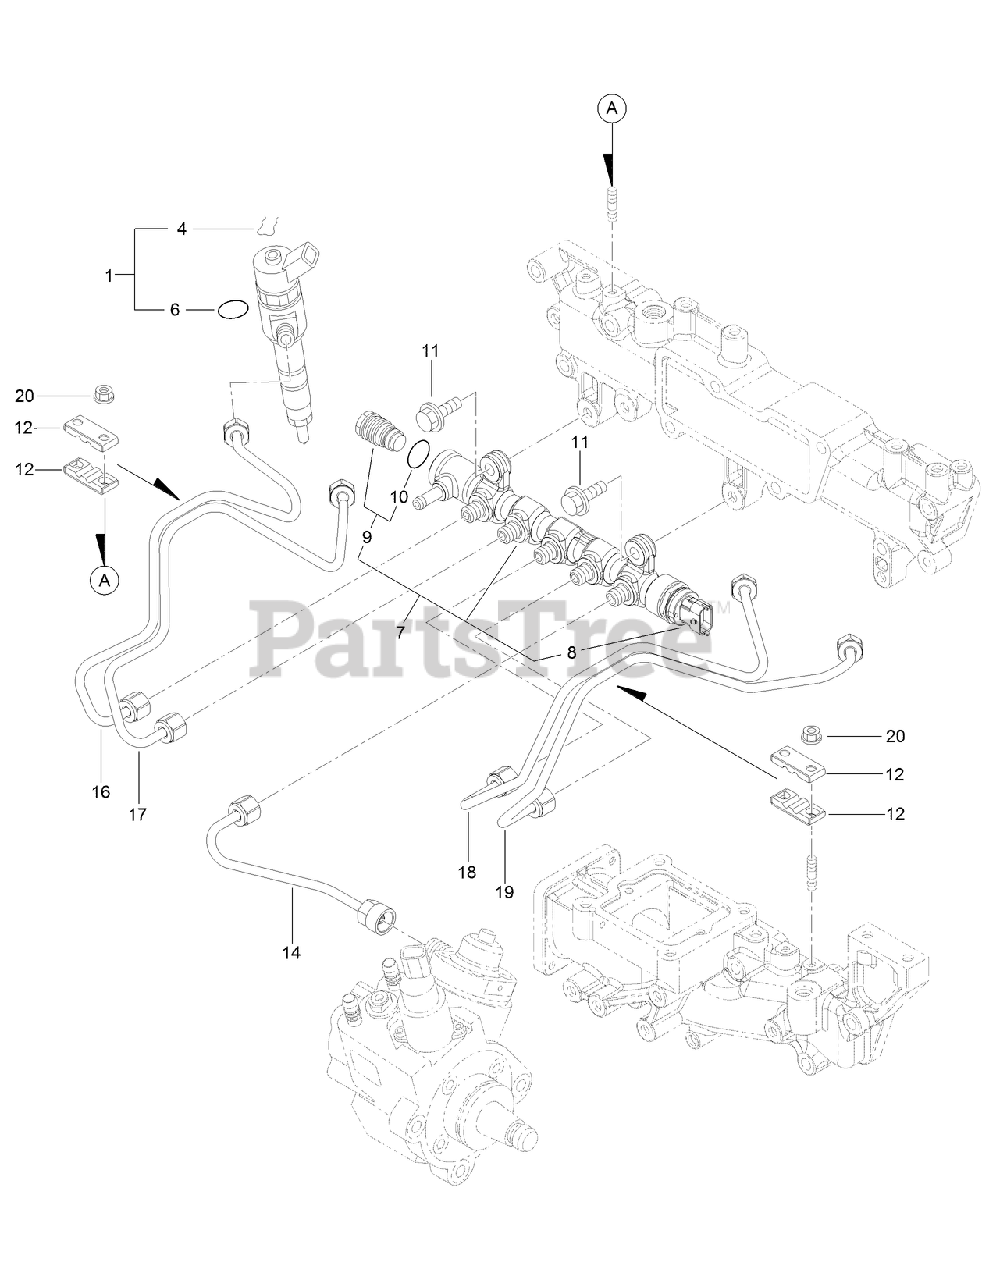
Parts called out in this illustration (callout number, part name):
1	INJECTOR-C R
4	RING-RETAINING
6	O-RING
7	RAIL ASM
8	SENSOR-PRESSURE, RAIL
9	VALVE ASM
10	O-RING
12	RETAINER
14	RAIL INJECTOR PIPE ASM
16	INJECTOR NO 1 PIPE ASM
17	INJECTOR NO 2 PIPE ASM
18	INJECTOR NO 3 PIPE ASM
19	INJECTOR NO 4 PIPE ASM
